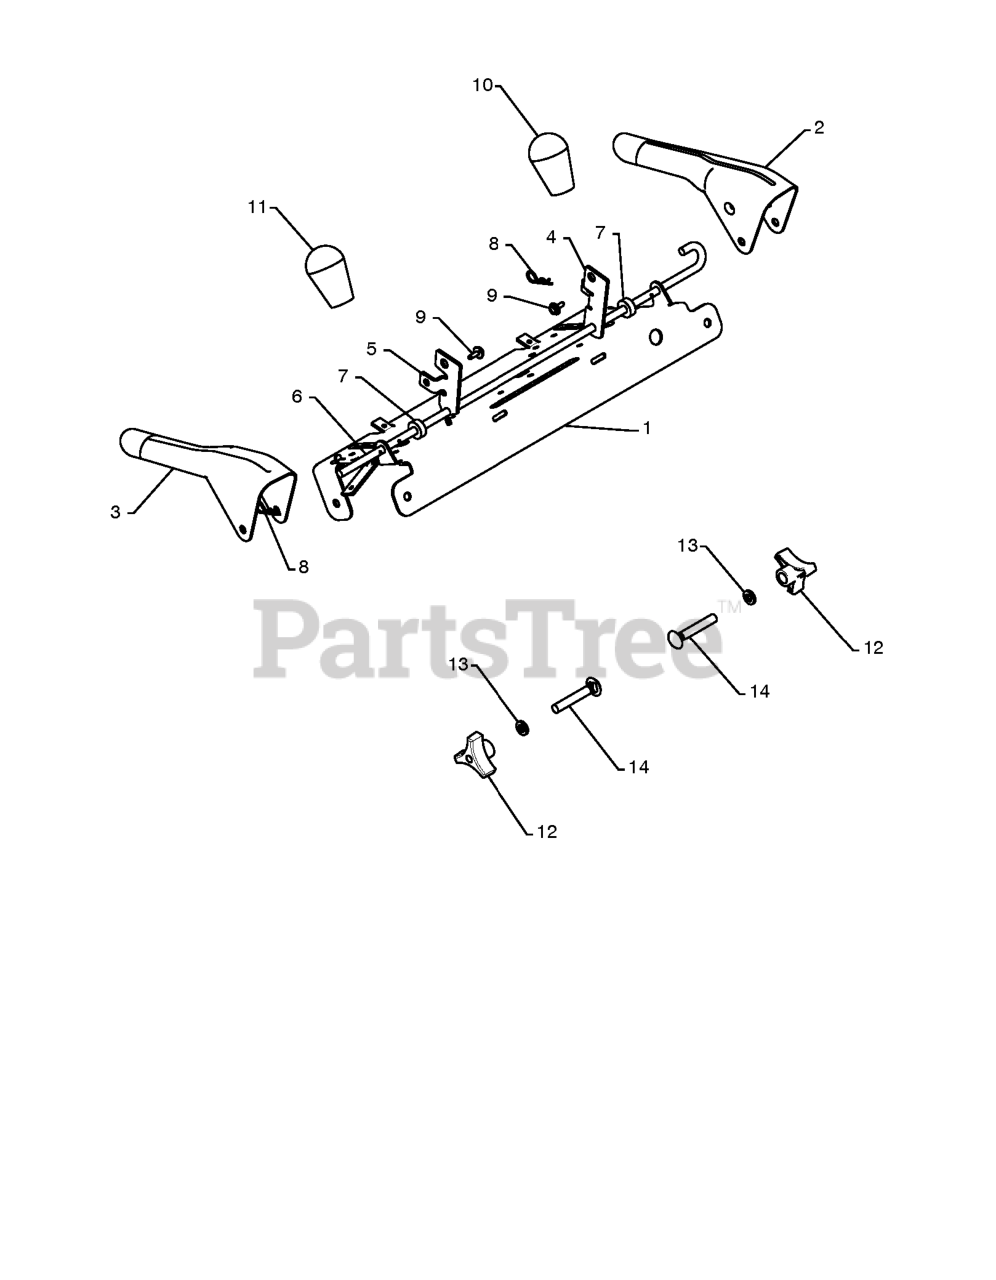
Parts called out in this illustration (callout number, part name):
1	PANEL.CONTROL.PNT.BLACK
2	LEVER.CONTROL.LH.
3	LEVER.CONTROL.RH.
4	ARM.TRACTION.ROD.YZ
5	ARM.IMPELLER.ROD.
6	BAIL.CONTROL.INTERLOCK
7	SPACER.CONTROL.LEVER
8	SPRING RETAINER
10	KNOB LEVER, BLACK
11	RED KNOB SHIFTER
12	KNOB.HANDLE.3/8.TRI-POINT.BLAC
13	WASHER
14	BOLT 3/8-16 X 2-1/4
